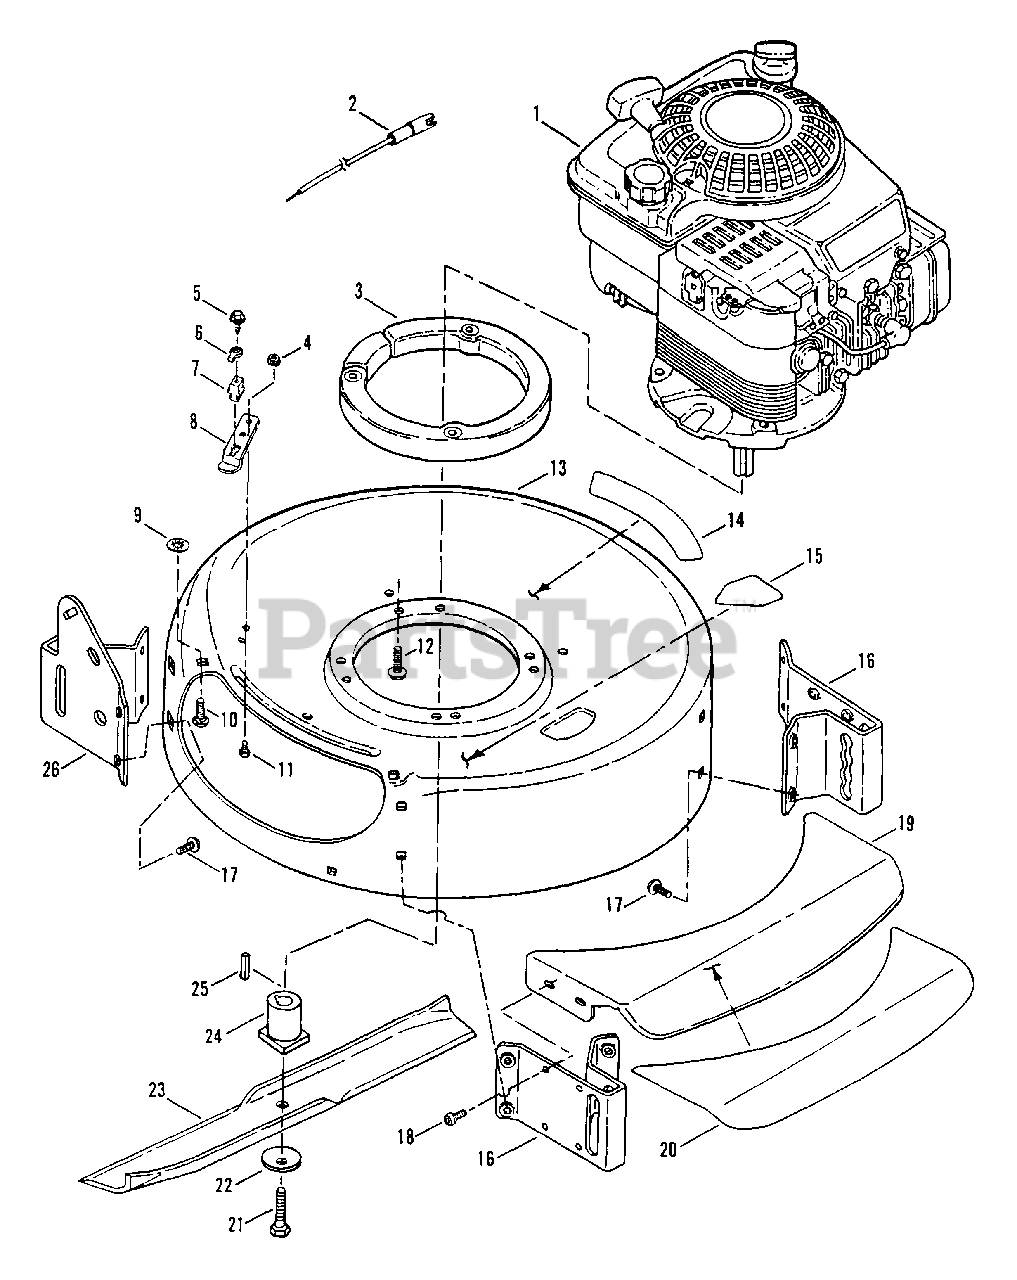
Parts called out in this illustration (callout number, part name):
2	WIRE, Ground
3	RING, Engine Mount
4	NUT, 1/4-20 Hex Flange Lock
5	SCREW, #8-18 x 3/4" Hex Washer Head
6	WASHER, #8 Tab Internal Tooth Lock
7	INSULATOR
8	SPRING, Interlock, (Short)
9	RETAINER, 5/16 Bolt
10	BOLT, 5/16-18 x 3/4" Short Neck Carriage, Grade 5
11	SCREW, 1/4-20 Hex Head Cap, Grade 5
12	SCREW, 3/8-16 x 2" Hex Washer Head, Self-Tapping
13	DECK, 20" Cutting
14	DECAL - WARNING
15	DECAL - DANGER (Keep Hands & Feet Away)
16	BRACKET, Front Wheels
17	SCREW, 5/16-18 x 1/2" Pan Head Torx, Self-Tapping
18	SCREW, #10-24 x 1/2" Hex Washer Self-Tap (Torx)
19	PLATE, Deck Front
20	DECAL, "Whipper" SNAPPER
21	SCREW, 3/8-24 x 2" Hex Head Cap, Grade 5
22	WASHER, Cone
23	BLADE, Mulching
24	HUB, Blade
25	KEY, #505 HI-PRO
26	BRACKET, Rear Wheel
